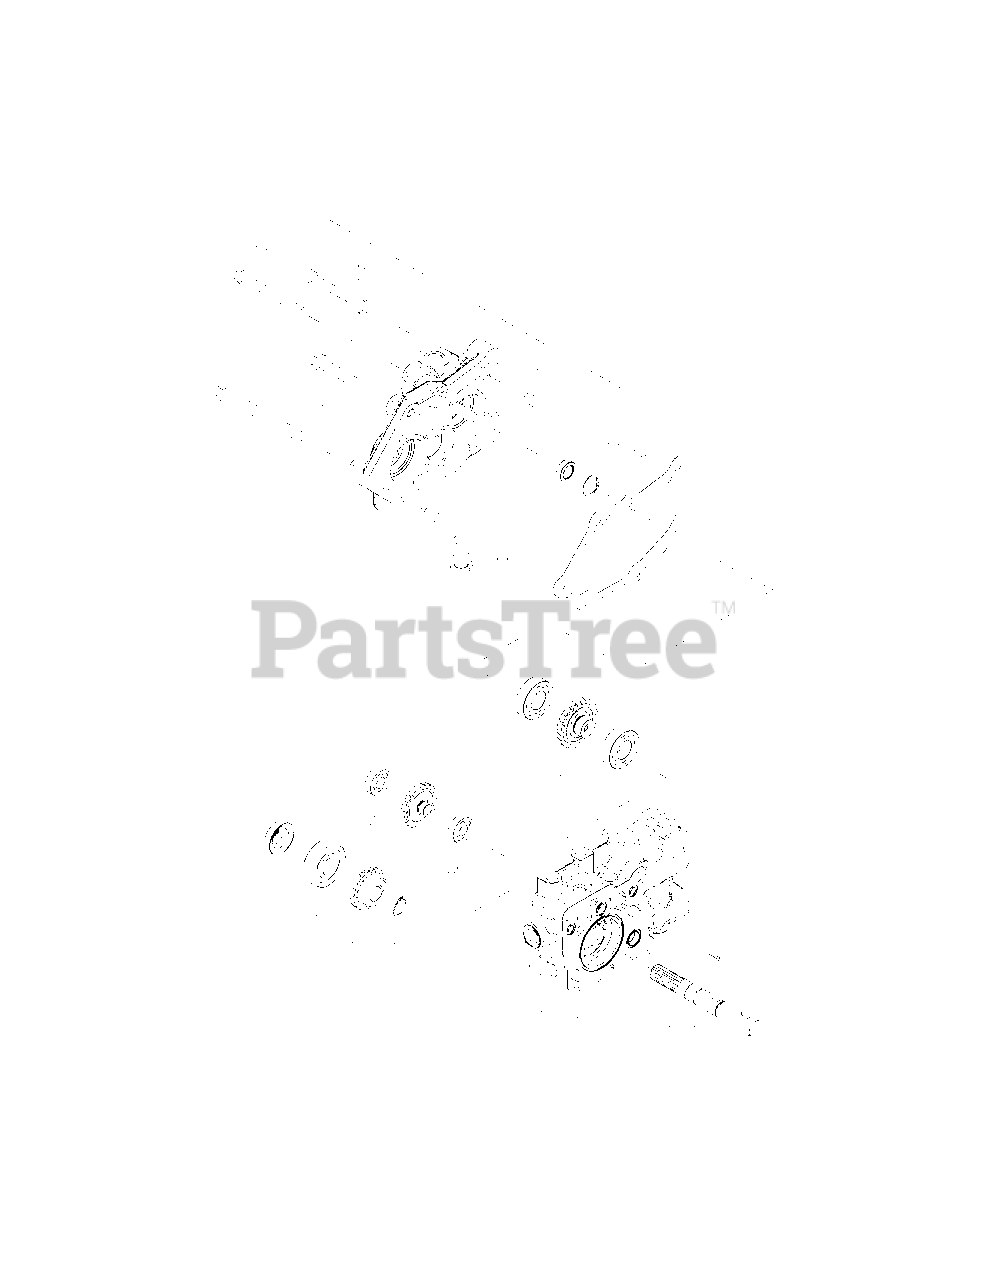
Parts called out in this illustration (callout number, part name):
3	Paking (Pump Cover
7	Pws-5Cg Sub Cmp
18	Packing, P 14.0
20	Seal, Tc122207
27	Seal, Tc173508
30	Bolt, 10 X 105
